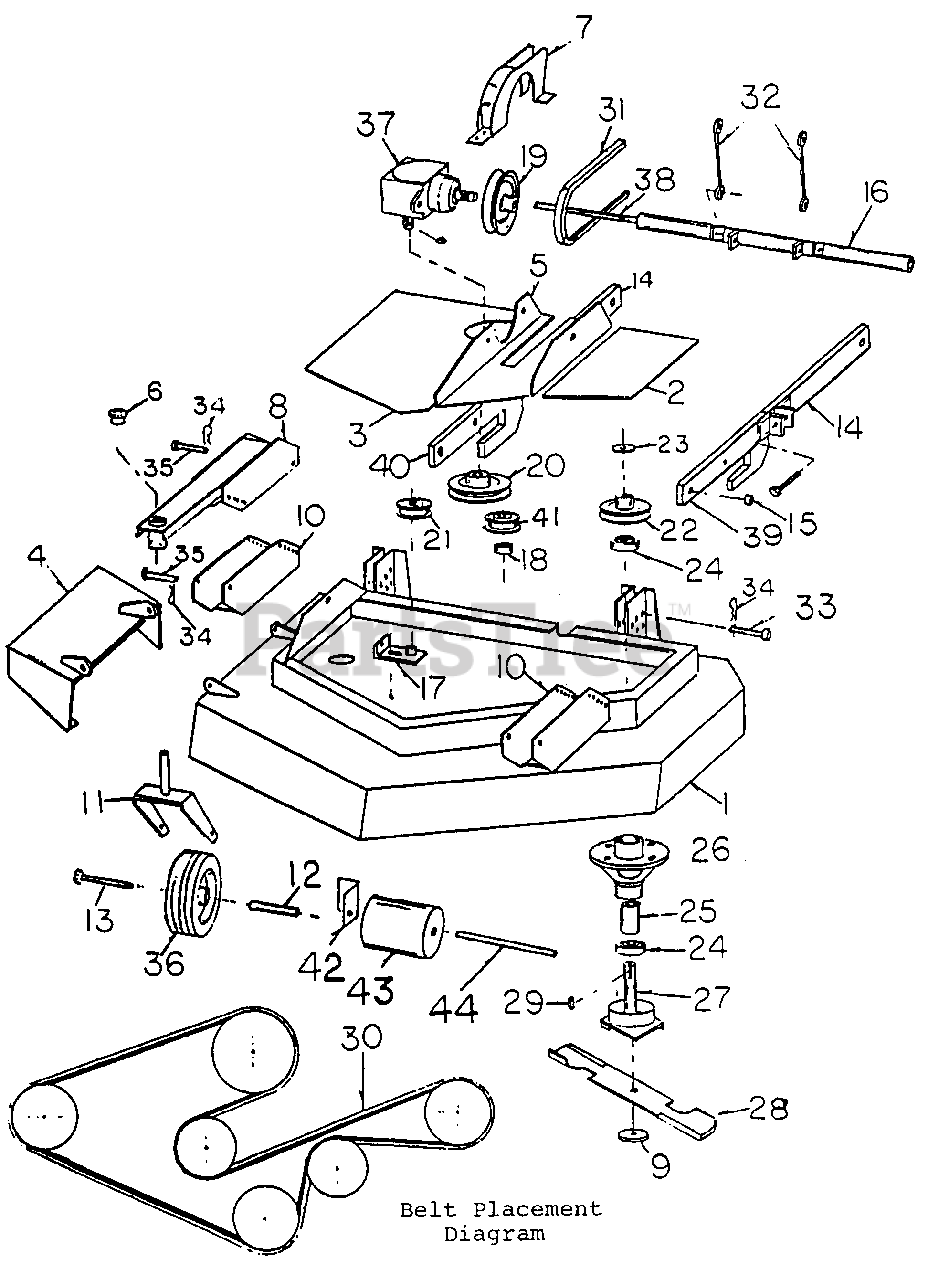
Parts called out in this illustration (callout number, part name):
1	MOWER DECK
2	COVER (Small)
3	COVER (Large)
4	FOOT GUARD
5	GEAR BOX MOUNT
6	GAGE WHEEL BUSHING
7	BELT GUARD
8	GAGE WHEEL MOUNT
9	SPRING WASHER
10	BRACKET, GAGE WHEEL MOUNT
11	FORK, GAGE WHEEL
12	AXLE, GAGE WHEEL
13	GAGE WHEEL BOLT
14	DECK LIFT ARM BACK ADJUSTABLE
15	BUSHING, DECK LIFT ARM
16	CROSSBAR
17	BELT TIGHTNER
18	SPACER, IDLER
19	PULLEY, GEAR BOX(Input)
20	PULLEY, GEAR BOX(Output)
21	PULLEY, IDLER TIGHTENER
22	PULLEY, SPINDLE
23	WASHER, SPINDLE
24	BEARING, SPINDLE
25	SPACER. SPINDLE
26	HOUSING, SPINDLE
27	SHAFT, SPINDLE
29	KEY, SPINDLE
30	DECK BELT
31	DRIVE BELT
32	CABLE, DECK
33	PINS, DECK
34	HAIR PINS
35	PINS, GAGE WHEEL
36	GAGE WHEEL
37	GEAR BOX
38	CROSS BAR PIN
39	L.H. 1 DECK LIFT ARM FRONT ADJUSTABLE L.H.
40	R.H. 1 DECK LIFT ARM FRONT ADJUSTABLE R.H.
41	IDLER PULLEY
42	ROLLAR BRACKET
43	RUBBER ROLLAR
44	ROLLAR SHAFT
